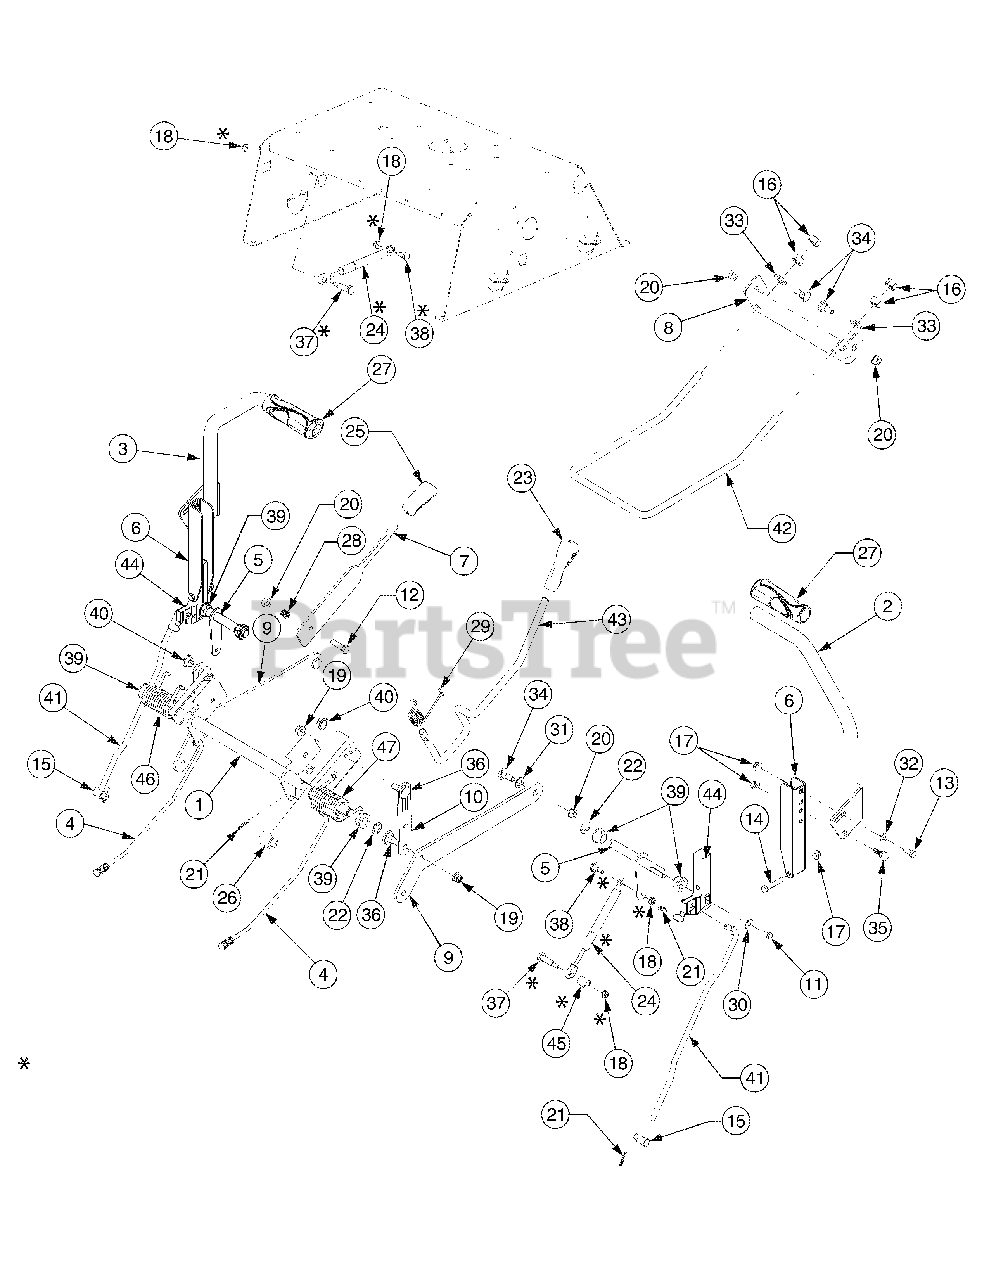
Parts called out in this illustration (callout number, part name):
1	Shaft Assembly, Deck Lift
4	Brake Rod
5	Control Shaft
6	Lapbar Pivot Bracket
7	Brake Han dle
9	Deck Lift Arm
11	Hex Bolt 1/4-20 x .625" Lg. Gr. 5
12	Hex Bolt 3/8-16 x 1.25
13	Hex Bolt 5/16-18 x .75" Lg. Gr. 5
14	Hex Screw 5/16-18 x 1.75" Lg.
15	Adjustment Ferrule 3/8-24
16	Hex Nut 1/2-13
17	Hex. Flanged L-Nut 5/16-18 Gr. F, Nylon
18	Hex. Flanged L-Nut Hex 1/4-20 Gr. F Ny lon
19	Hex. Flanged L-Nut 3/8-16 Gr. F Ny lon
20	Hex. Flanged L-Nut 3/8-16 Gr. F
21	Int. Cotter Pin .072 x 1.13" Lg.
22	E-ring
23	Handle Grip
24	Cylinder, Damper
25	Handle Grip
26	Spacer .62 x 1.0
27	Hand Grip, Soft Touch
27	Hand Grip, 5.0 LG Standard
28	Compression Spring
29	Torsion Spring
30	Cupped Washer .265 ID x .75 OD x .062
31	Flat Washer .53 ID x 1.00 OD x .06
32	Flat Washer .34 ID x .688 OD x .065
33	Flat Washer .531 ID x 1.0 OD
34	Shld. Scr. .500 Dia. x .335" Lg.
35	Shoulder Screw
36	Shoulder Screw .50 Dia.
37	Shoulder Screw .375 x 1.16
38	Shoulder Screw .375 x .38:1/4-20
39	Hex Flange Bearing .630 ID
40	Flange Bearing .626 x .938 x .344
41	Lapbar Control Rod
42	Deck Front Hanger Rod
43	Deck Lift Handle Rod
44	Control Hub
45	Spacer, .385 x .63 x .75
46	Torsion Spring LH
47	Torsion Spring RH
